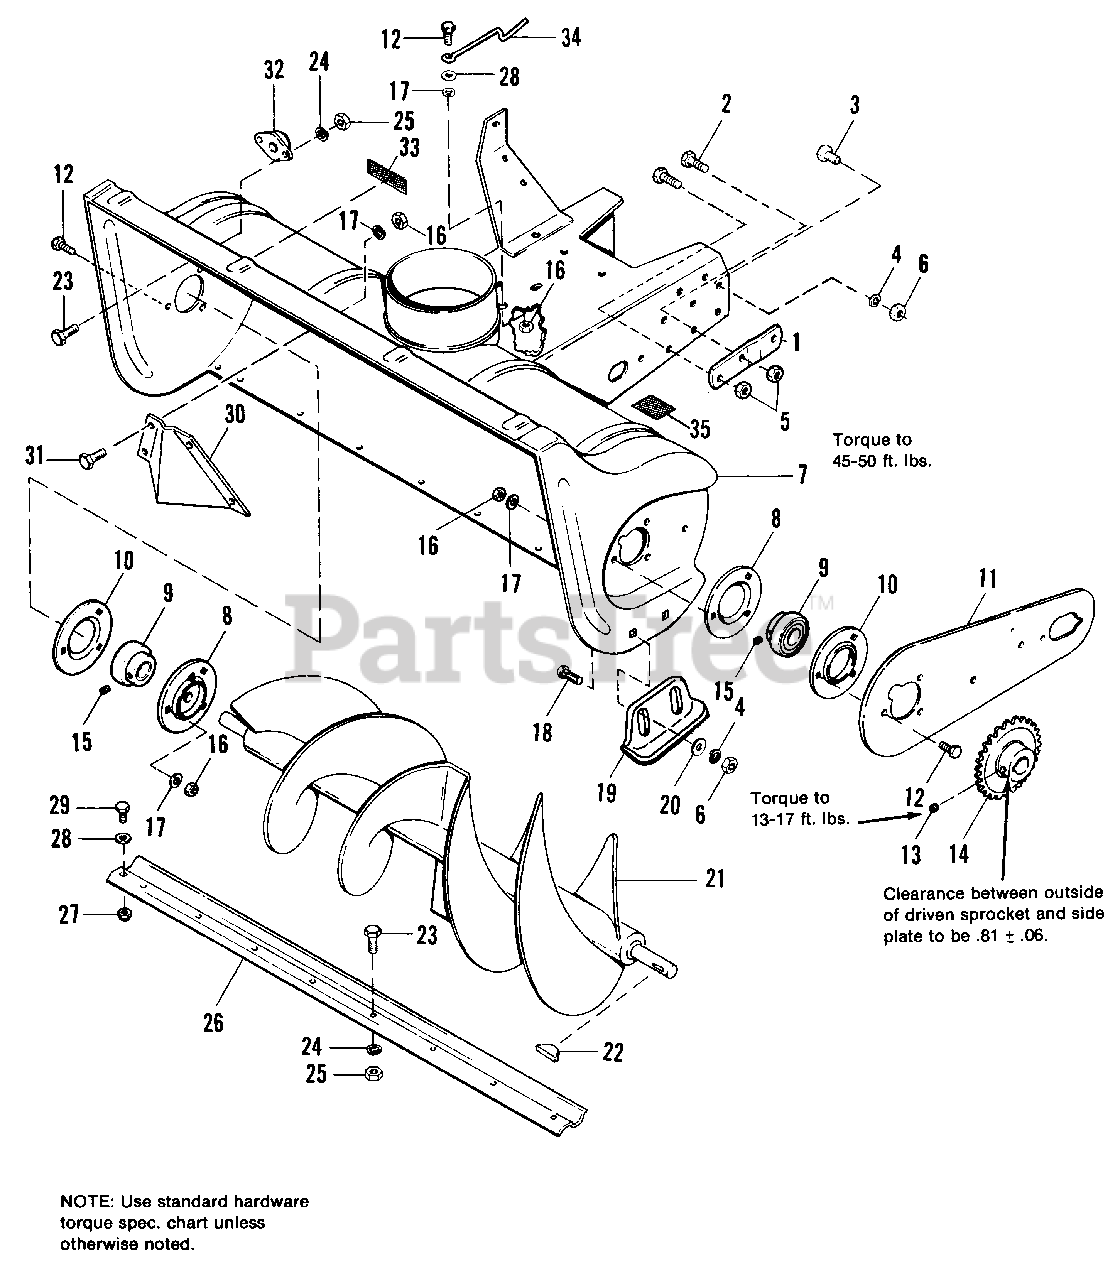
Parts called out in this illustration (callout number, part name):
1	CLIP, Frame
2	CAPSCREW, Hex Hd., 7/16-14 x 1
3	CAPSCREW, Hex Hd., 3/8-16 x 5/8
4	LOCKWASHER, 3/8
5	LOCKNUT, Flange, 2-Way Lock, 7/16-14
6	NUT, 3/8-16
7	BODY & FRAME ASSY., (36" only)
7	BODY & FRAME ASSY., (42" only)
8	FLANGE, Bearing, w/Fitting
9	BEARING, Cartridge
10	FLANGE, Bearing
11	PLATE, Side
12	CAPSCREW, Hex Hd., 5/16-18 x 3/4
13	SETSCREW, Socket Hd., 5/16-18 x 5/16
15	SETSCREW, 1/4-28 x 1/4
16	NUT, Hex, 5/16-18
17	LOCKWASHER, 5/16
18	CARRIAGE BOLT, 3/8-16 x 3/4
20	WASHER, Plain, 3/8
21	ROTOR ASSY. (36" only)
21	ROTOR ASSY. (42" only)
22	KEY, Hi-Pro
23	CAPSCREW, 1/4-20 x 5/8 (Qty. 9 on 36" only)
24	LOCKWASHER, 1/4 (Qty. 9 on 36" only)
25	NUT, Hex, 1/4-20 (Qty. 9 on 36" only)
26	SCRAPER, Body (36" only)
26	SCRAPER, Body (42" only)
27	LOCKNUT, 5/16-18
28	WASHER, Plain, 1/4
29	CAPSCREW, Hex Hd., 5/16-18 x 5/8, Gr. 5
31	CAPSCREW, Hex Hd., 5/16-18 x 5/8
33	DECAL, Safety
34	STOP, Belt
35	DECAL, Danger
